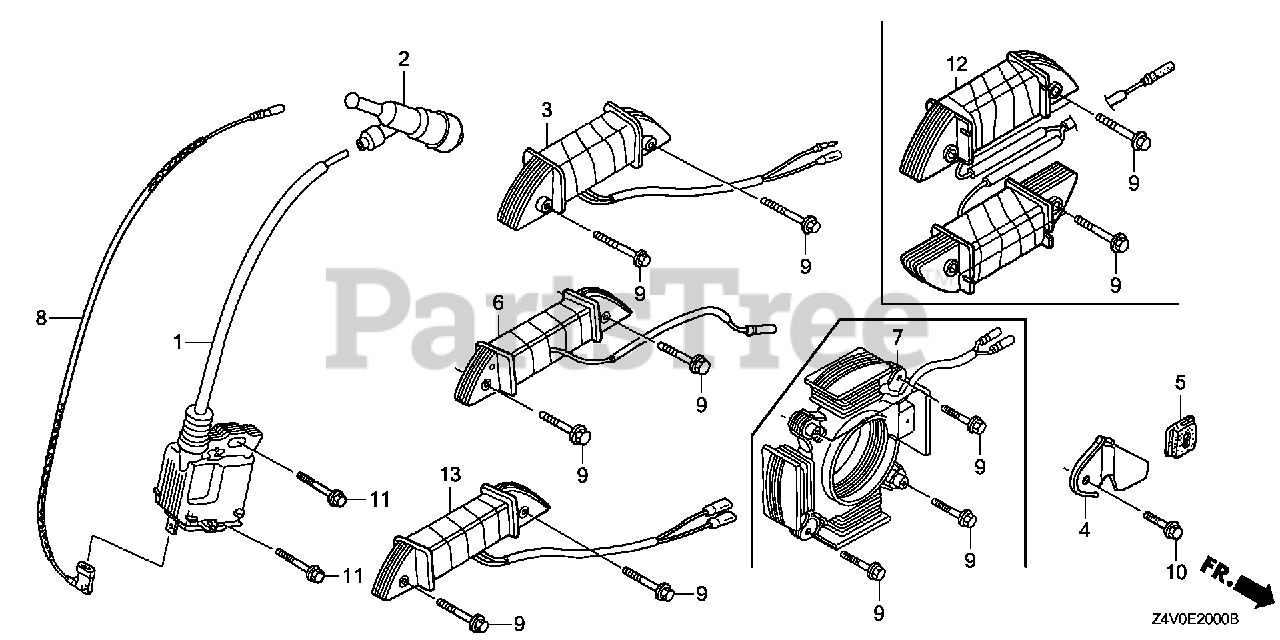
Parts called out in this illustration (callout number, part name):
1	COIL ASSY., IGNITION (TEC)
2	CAP ASSY., NOISE SUPPRESSOR (NGK)
2	CAP ASSY., NOISE SUPPRESSOR (TEC)
8	WIRE, STOP SWITCH (370MM)
11	BOLT, FLANGE (6X25) (CT200)
